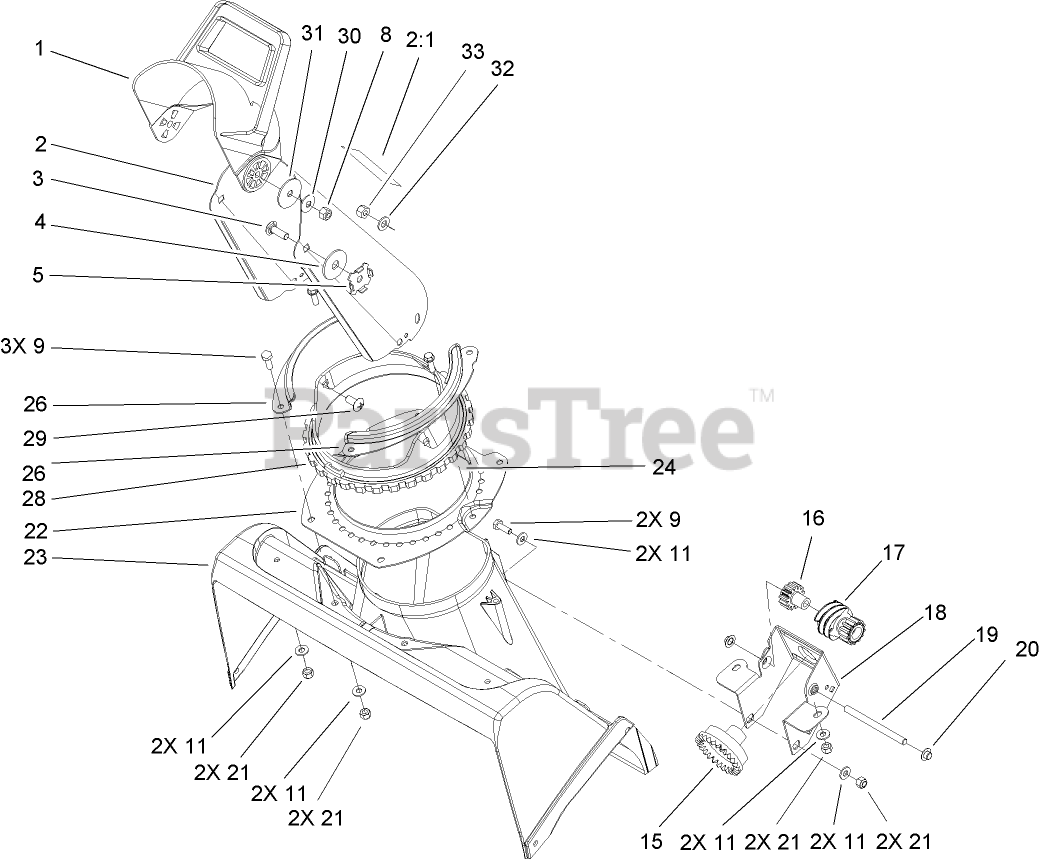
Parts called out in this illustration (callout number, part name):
1	CHUTE-DEFLECTOR
2	CHUTE ASM
2:1	DECAL-DANGER
3	SCREW-CARR
4	WASHER-RUBBER
5	PLATE-FRICTION
8	NUT-LOCK, NI
9	SCREW-HH
11	WASHER-FLAT
15	GEAR-FACE
16	GEAR-SPUR, SPACER
17	GEAR-SPUR/WORM
18	BRACKET-GEAR, CHUTE
19	SHAFT-GEAR, WORM
20	NUT-PUSH
21	NUT-LOCK, NI
22	RING-SUPPORT, CHUTE
23	HOUSING-ROTOR, UPPER
24	SCREW-HWH
26	RING-RETAINER, CHUTE
28	RING-GEAR, CHUTE
29	SCREW-TRUSS HD, PHILLIPS
30	WASHER-BELLEVILLE
31	WASHER-FLAT
32	WASHER-FLAT
33	NUT-LOCK, NI
